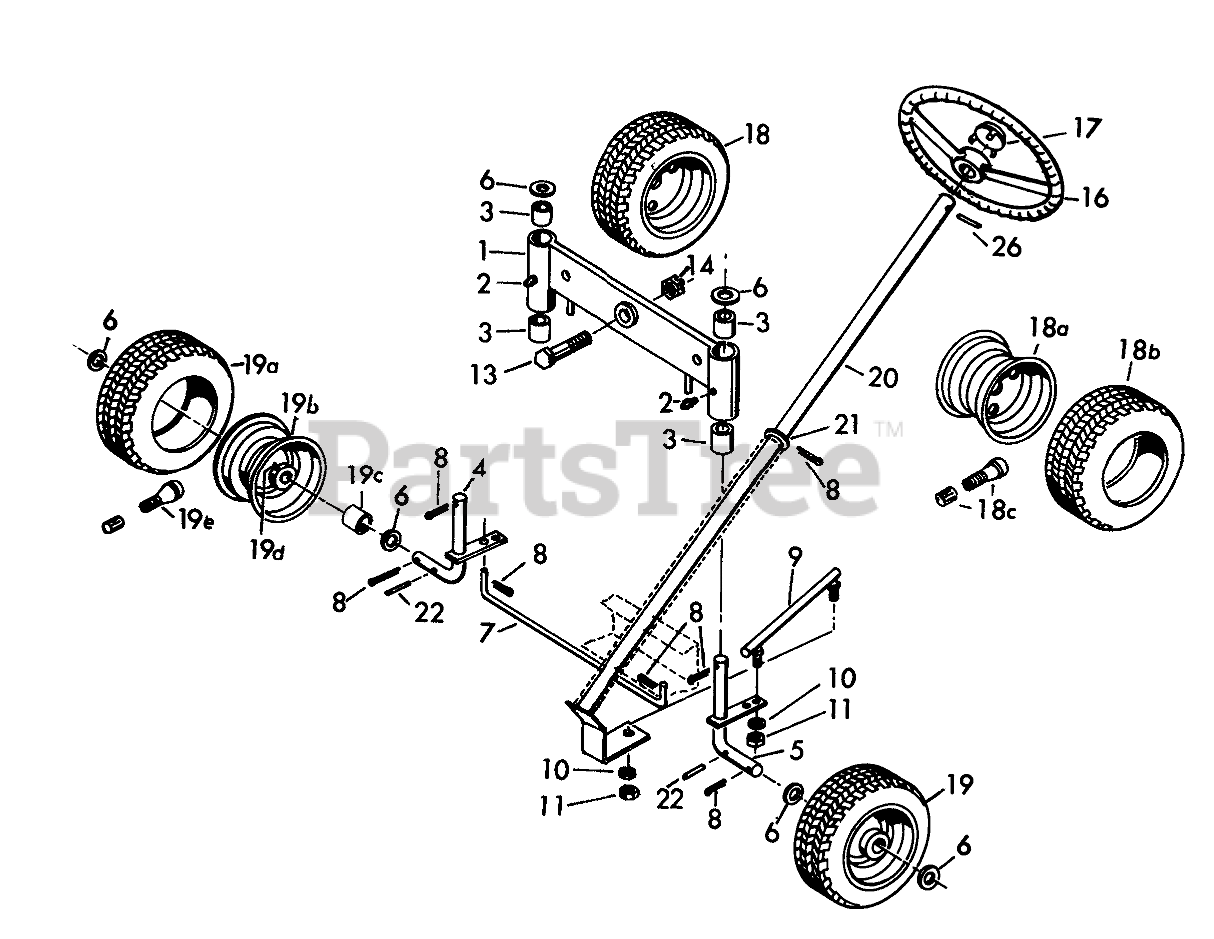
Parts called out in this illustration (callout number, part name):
1	Front Axle Housing
2	Grease Fitting
3	Bushing
4	Axle-Right Hand
5	Axle-Left Hand
6	Washer
7	Tie Rod
8	PIN-COTTER
9	Ball Joint Assembly
10	WASHER-LOCK
11	NUT-HEX
14	Nut
16	Steering Wheel
17	Steering Wheel Cap
18	Rear Wheel Assembly Consists of
19	Front Wheel Assembly Consists of
20	Steering Post
21	Washer
23	PIN-COTTER
26	PIN-ROLL
